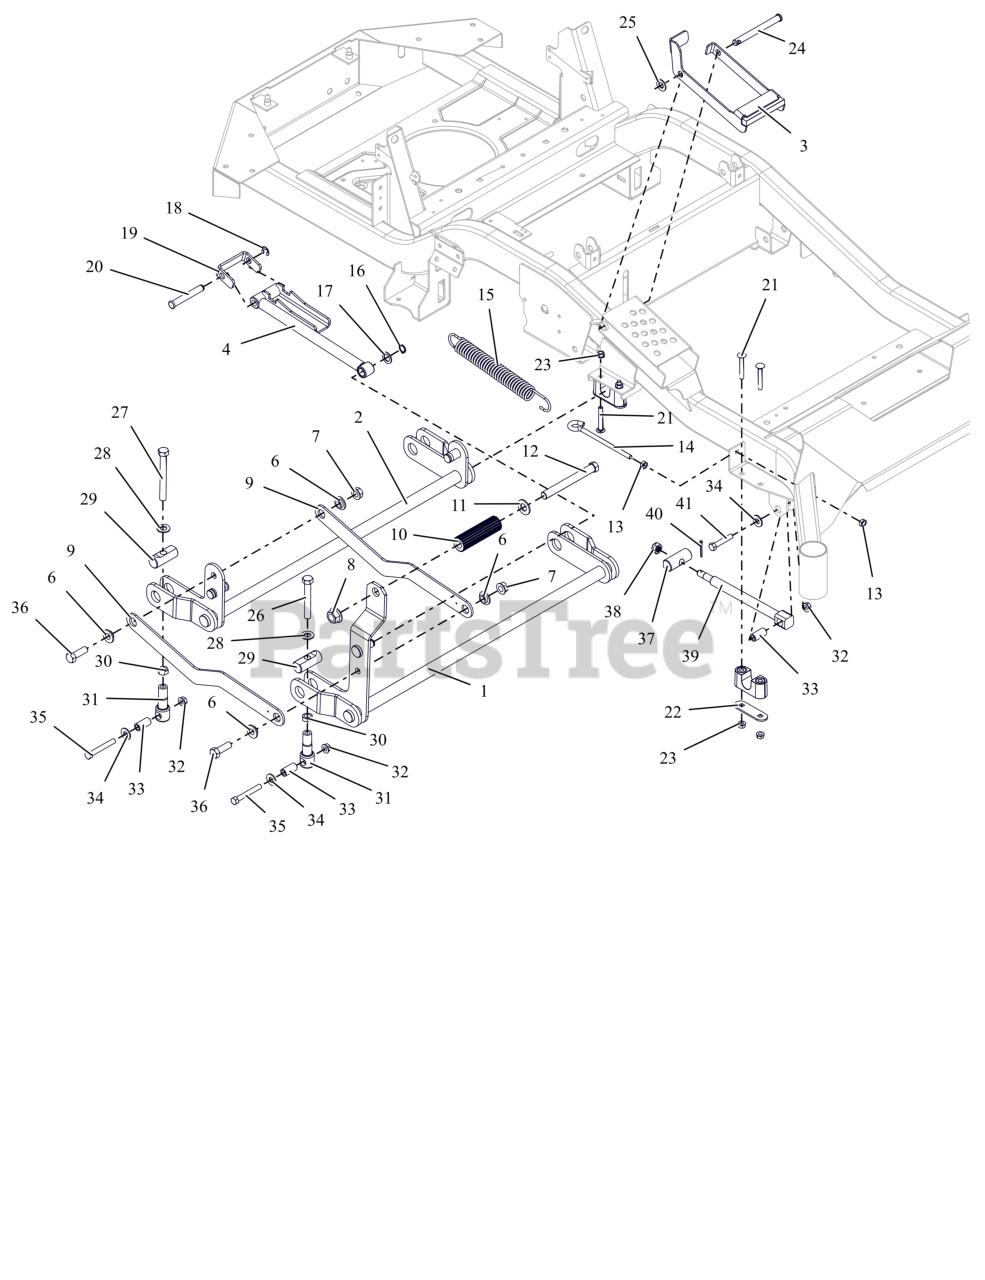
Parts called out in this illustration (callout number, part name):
1	WLDMT, FRONT DECK LIFT PIVOT
2	WLDMT, REAR DECK LIFT PIVOT
3	BRKT, HOC TRANSFER LOCK
4	WLDMT, HOC ARM
5	ASM-BUSHING, DECK LIFT
6	BSHG-FLG .515X.750X.395X1.120
7	NUT-LK-TOP-FLG .500-13 GF ZCC
8	NUT,FLG-TOP LK .625-11 FBP
9	LINK, DECK LIFT
10	ROD, FOOT PEDAL (BLACK)
11	WSHRFLT 5/8SAE CARBHARD FBP
12	BLT, HEX .62-11X5.50 G5 FBP
13	NUT-JAM .375-16 G2 ZCC
14	BOLT,.38-16 X 5.25-.62 DIA EYE
15	SG-TENS .162X1.25X8.25 WLD 25
16	RG-RTNG-EXT .625X.050
17	WSHR, FLT .630X1.005X.062 ZCC
18	RG-RTNG-EXT .500X.042 (E)
19	BRKT, HOC LINE
20	PIN, .499/.494 x 3.385 CLEVIS
21	BLT, RHSSN.31-18X2.25 G5 ZCC
22	PLATE, BEARING SUPPORT
23	NUT,LK-CTR-FLG .31-18 GF ZCC
24	PIN-SLIC .50X4.97X4.55 -ZCC
25	WSHR-FL-NYL .518X1.000X.080
26	BLT, HEX .50-13X3.50F G5 ZCC
27	BLT, HEX .50-13X4.50F G8 ZCC
28	WSHR, FLT .557X1.040X.102 ZCC
29	PIN, DECK LIFT
30	NUT-JAM .500-13 G2 ZCC
31	LINK, DECK LIFT FORMED
32	NUT-LK-TOP-FLG .38-16 ZC120
33	SPACER, DECK LEVELING
34	WSHR,FLT .438X1.00X.083 ZCC
35	BLT, HEX .38-16X2.75 G8 ZCC
36	BLT,HEX .50-13X1.50 G5 ZCC
37	PIN, DECK LIFT
38	NUT-SL .50-13
39	DRAG,LINK-HD
40	PIN,CTR.12X1.25EXTPRSQCT ZC120
41	BLT,HEX .38-16X2.00 G5 ZCC
